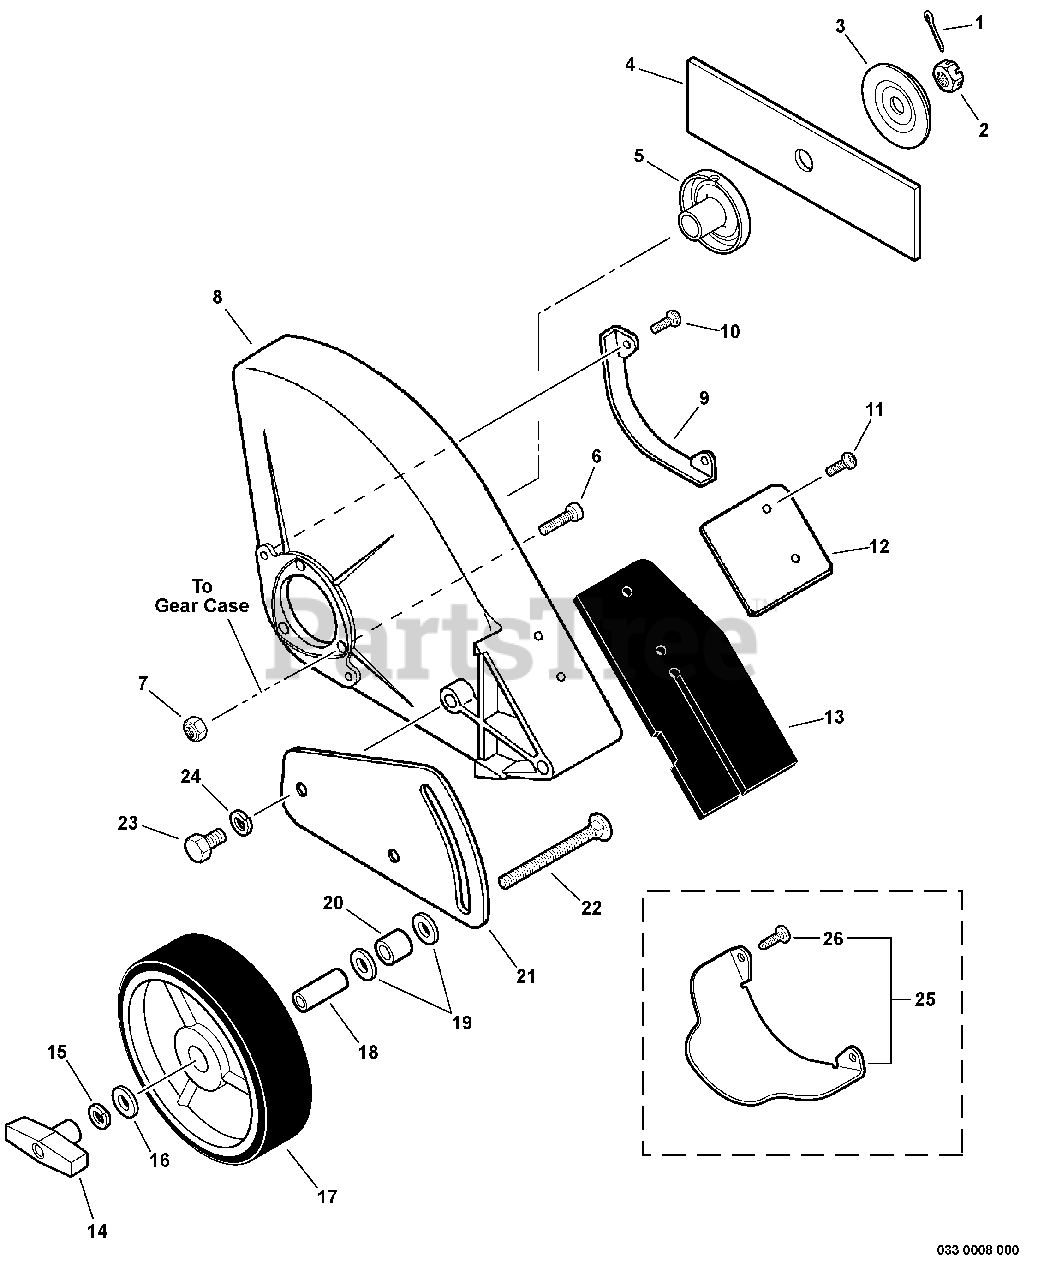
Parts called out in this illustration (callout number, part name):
1	PIN, COTTER 2×22
2	NUT 10×1.25 LH
3	PLATE, ADAPTOR - LOWER
4	BLADE - 2 PK
5	PLATE, ADAPTOR - UPPER
6	BOLT, TORX 5×20
7	NUT, LOCK M5
8	SHIELD, BLADE
9	GUARD, SHIELD
10	BOLT, TORX 4×12
11	BOLT, TORX 4×12
12	PLATE, FLAP
13	FLAP, DEBRIS
14	KNOB, FASTENER
15	WASHER, SPRING 8
17	WHEEL
18	COLLAR 12
19	COLLAR 8
20	WASHER, SPRING 10
21	BRACKET, WHEEL
22	BOLT 5/16"-18×3"
23	BOLT 8×14
24	WASHER, SPRING 8
25	GUARD KIT, SHIELD
26	SCREW 4×12
